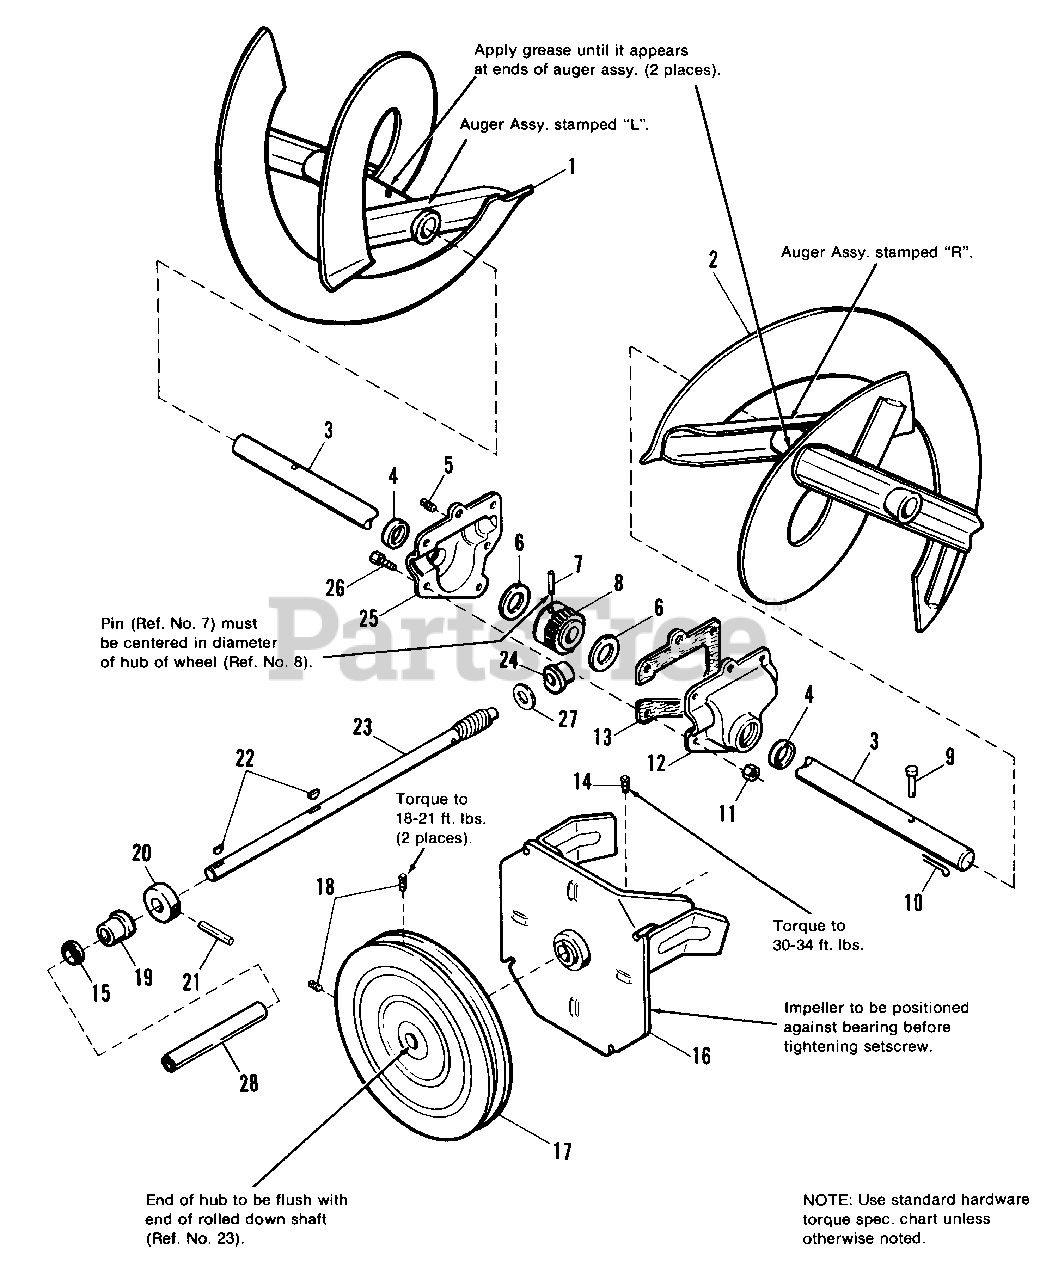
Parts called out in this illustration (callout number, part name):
1	AUGER ASSY., L.H., 24"
1	AUGER ASSY., L.H., 28"
1	AUGER ASSY., L.H., 80 32"
2	AUGER ASSY., R.H., 24"
2	AUGER ASSY., R.H., 28"
2	AUGER ASSY., R.L., 32"
3	SHAFT, Auger
5	PLUG, Pipe, 1/8
6	WASHER, Thrust
7	PIN, Drivelok, 5/16 x 1-1/2
8	WHEEL, Worm
9	PIN, Shear
10	PIN, Cotter, 3/32 x 3/4
11	LOCKNUT, Hex, 1/4-20
12	CASE, Gear, R.H.
14	SETSCREW, Sq. Hd., 3/8-16 x 1/2
16	IMPELLER ASSY.
17	PULLEY, Auger Input
18	SETSCREW, Sq. Hd., 5/16-18 x 1/2
19	BUSHING, Flange
20	COLLAR, Thrust
21	PIN, Drivelok, 3/16 x 1-1/2
22	KEY, Woodruff, 3/16 x 5/8
23	SHAFT, Roller Worm
24	BUSHING, Flange
25	CASE, Gear, L.H.
26	CAPSCREW, Hex Hd., 1/4-20 x 7/8
27	WASHER, Thrust
